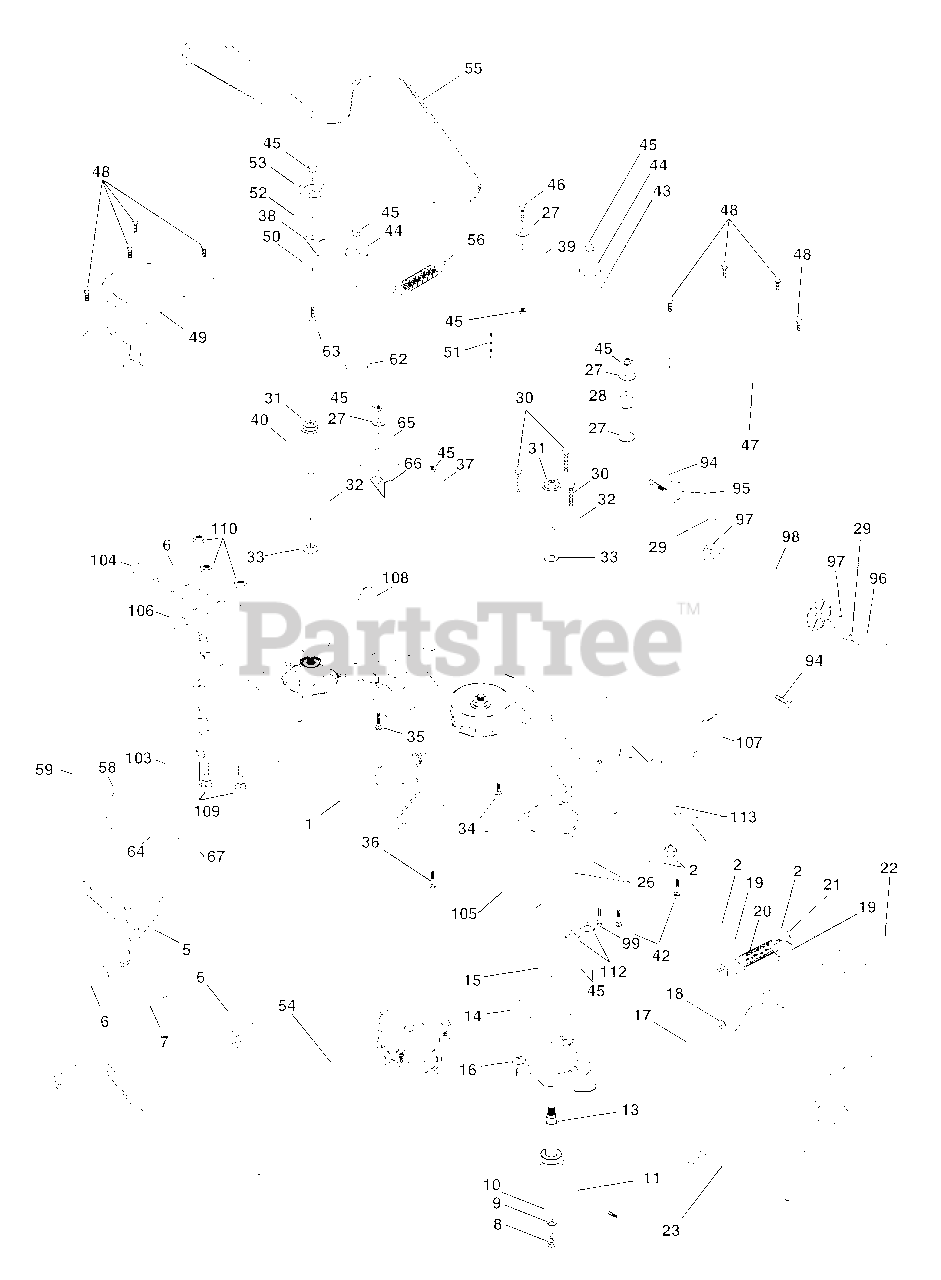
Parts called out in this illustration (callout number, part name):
1	Deck Weldment 50"
2	Nut, Crownlock 5/16-18
5	Bracket Asm., Sway Bar
6	Retainer, Spring
7	Arm Suspension, Rear
8	Bolt 3/8-24 x 1.25 Gr. 8 Patched
9	Washer, Lock Hvy 3/8 Unplated
10	Washer, Hard Blade Mower Vented
11	Blade (3 Required)
13	Shaft Asm., W/Lower Brg
14	Housing, Mandrel 50" Vent
15	Bearing, Ball Mandrel
16	Stripper, Mower Vented
17	Rod, Hinge
18	Washer 11/32 x 5/8 x 16 Ga.
19	Cap Sleeve
20	Spring, Torison Delector
21	Bracket, Deflector
22	Nut, Push
23	Shield, Deflector Mower
26	Bolt Rd Hd Sht Sqnk
27	Washer 13/32 x 13/16 x 16 Ga.
28	Spacer, Spring Stop Idler
29	Nut, Lock Hx W/Ins 5/16-18
30	Screw Thd Rolling Washer Head
31	Nut, Flg Top Lock Cntr 9/16
32	Pulley, Mandrel
33	Washer, Spacer Mower Vented
34	Bolt, Carriage 3/8-16 x 1-1/4
35	Bolt, Carriage 3/8-16 x 2
36	Bolt, Carriage 3/8-16 x 1 Gr. 5
37	Stiffener, Arm Idler
38	Keeper, Belt Idler
39	Pulley, Idler Flat
40	Pulley, Driven
42	Bolt, Carriage 5/16-18 Unc x 3/4
43	Arm, Idler Secondary
44	Spacer, Retainer
45	Nut, Crownlock 3/8-16 Unc
46	Bolt, Fin Hex 3/8-16 Unc x 1-3/4
47	Cover, Mandrel RH
48	Screw, Thd Roll 1/4-20 x 5/8
49	Cover, Mandrel LH
50	Arm, Idler Primary
51	Spring, Secondary
52	Pulley, Idler V Groove
53	Shield, Idler
54	V-Belt, Mower Primary
55	V-Belt, Mower Secondary
56	Spring, Primary
58	Wheel, Gauge
59	Bolt, Shoulder
62	Washer Hardened
63	Bolt Carriage 3/8-16 x 1-1/2
64	Washer 3/8 x 7/8 x 14 Ga.
65	Pulley Idler Flat Mower
66	Keeper, Belt Idler 50" Vent
67	Nut, Center Lock 3/8-16
94	Bolt Hex Hd 5/16-18 x 1
95	Bracket, Asm. Noseroller LH
96	Bracket, Asm. Noseroller RH
97	Washer 17/32 x 7/8 x 16 Ga.
98	Roller, Nose
99	Bolt, Carriage 3/8-16 x 1-3/4 Gr. 5
103	Bar Adj. Gauge Wh.
104	Pin Head Rivot
105	Bracket Ga Wh Asm RH 50
106	Bracket Ga Wh Asm LH 50
107	Bracket Ga Wh Assy F RH 50
108	Bracket Ga Wh Assy F LH 50
109	Bolt Carraige 5/16- 18 x 5/8
110	Nut Crownlock 5/16-18
112	Washer 17/32 x 3/4 x 16 Ga.
113	Bolt Carriage 5/16-Unc 1/2
